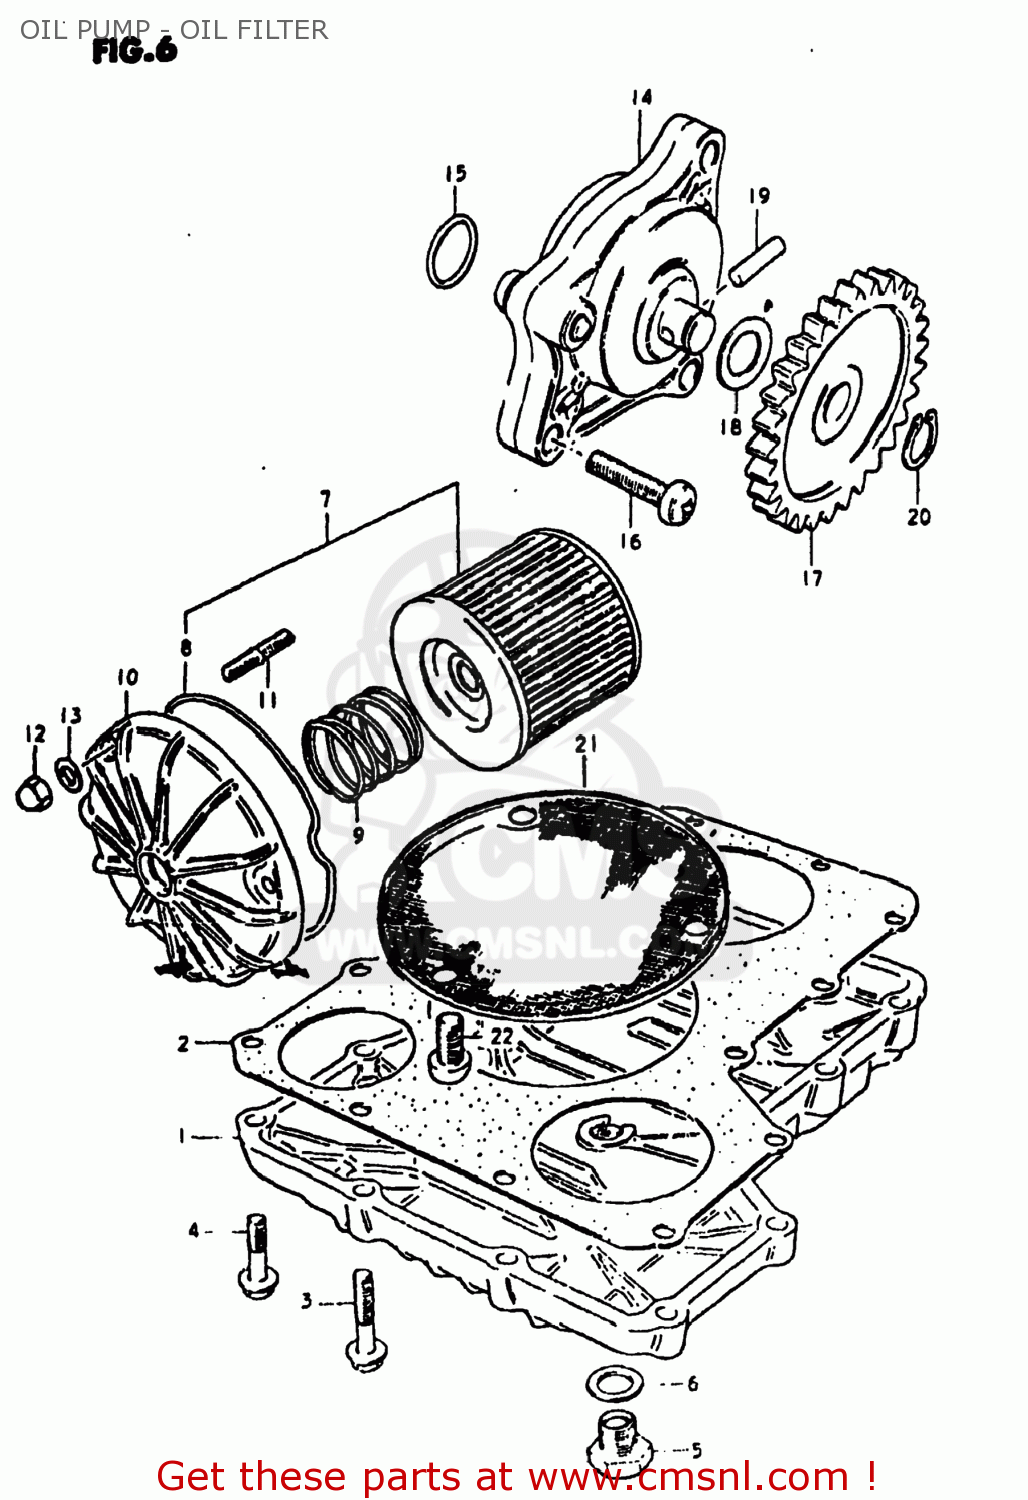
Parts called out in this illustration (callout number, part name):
1	PAN,OIL
2	GASKET,OIL PAN (MCA)
3	BOLT
4	BOLT
5	PLUG
6	GASKET(14X19.2X2) (NAS)
7	FILTER ASSY,ENGINE OIL
8	O RING,OIL FILTER CHAMBER CAP
9	SPRING
10	CAP,OIL FILTER
11	STUD 6X20
12	NUT
13	WASHER
14	PUMP ASSEMBLY,OIL
15	O RING(D:1.9,ID:13)
16	SCREW
17	GEAR,OIL PUMP DRIVEN
18	SHIM
19	PIN(4X15.8)
20	CIRCLIP
21	STRAINER,ENGINE OIL
22	SCREW 6X12
